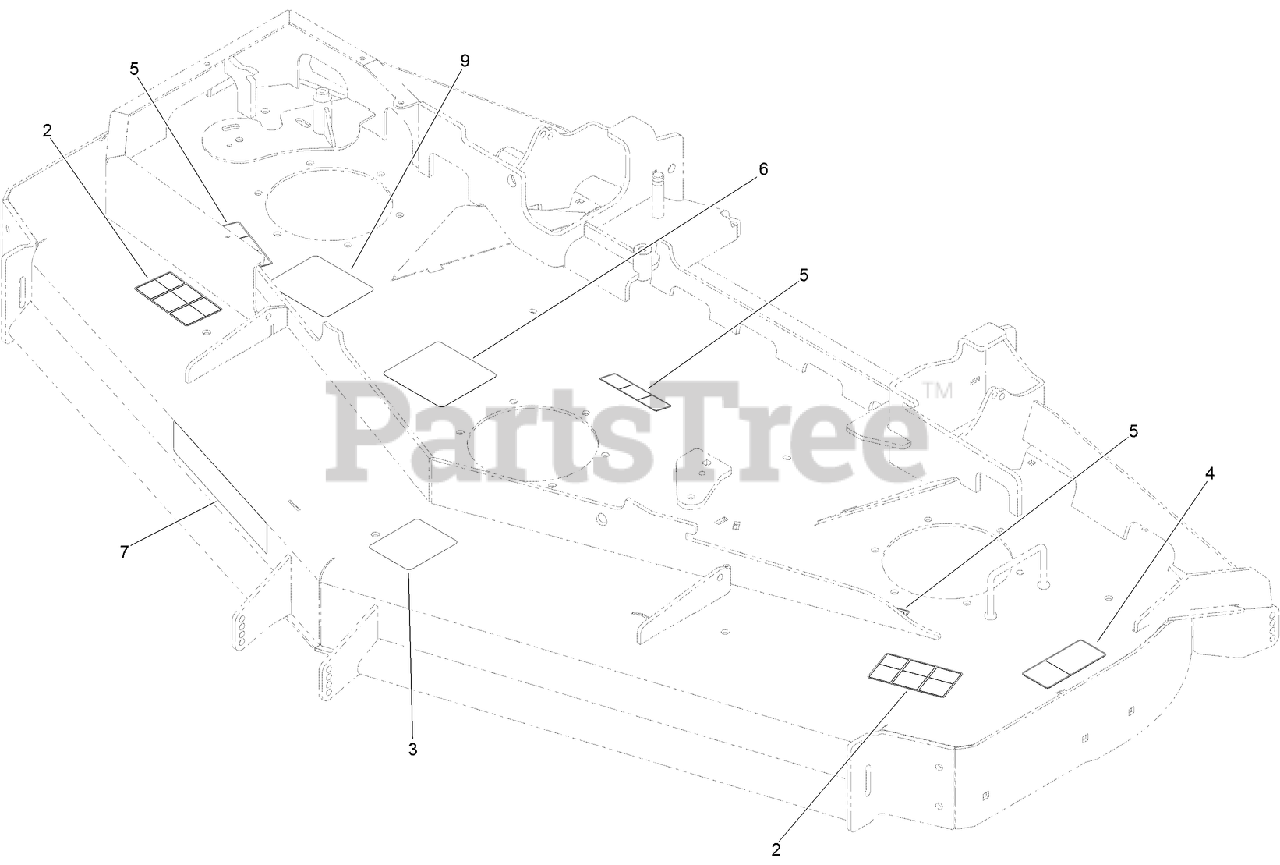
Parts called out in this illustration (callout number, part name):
2	DECAL-DANGER
3	DECAL-ROLLER, ANTI-SCALP
4	DECAL-TORQUE, BLADE BOLT
5	DECAL-MISSING, COVER
6	DECAL-ROUTING, DECK BELT
9	DECAL-SPINDLE, COUNTER ROTATING
